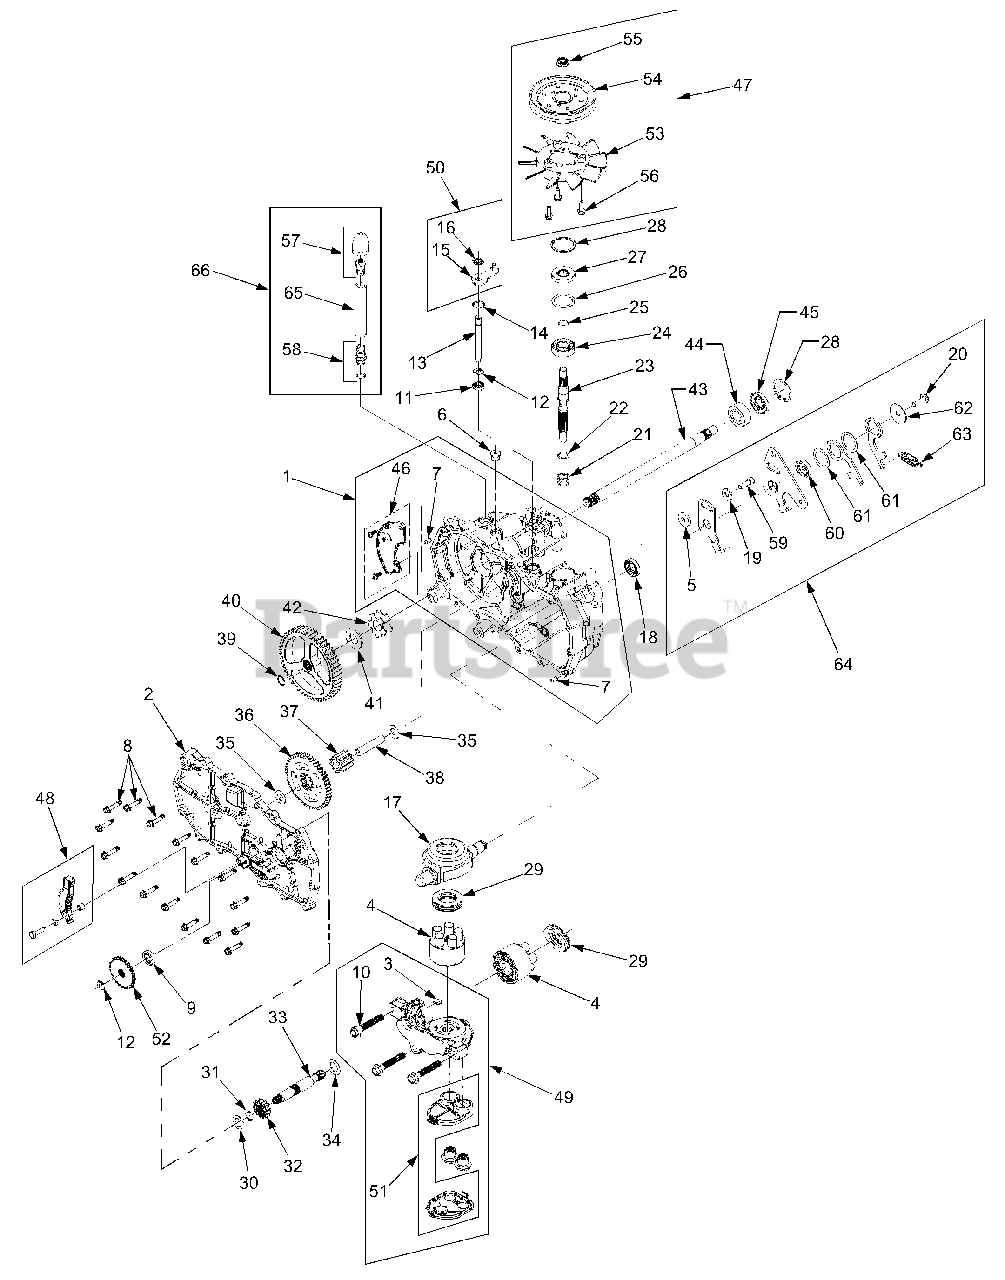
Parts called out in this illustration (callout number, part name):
1	Housing Assembly, Main
2	Side Assembly,
3	Plate, Bypass
4	Block Assembly
5	Spacer, .32 x 1.005
8	Screw, Hex Self Tapping, 1/4-20 x 1.25
9	Seal, Lip, .625 x 1.0 x .25
10	Bolt, Hex Flange, 3/8-24 x 2.5
11	Seal, Lip, .375 x .75 x .25
12	Ring, Retaining, .375 Ext.
14	Ring, Retaining, .75 Int.
16	Ring, Retaining, .375 Push
17	Swashplate, Trunnion
18	Seal, Lip, 18 x 32 x 7
19	Washer, Flat, 11/32 x 7/8 x 1/16
20	Screw, 5/16-24 x 1.0
21	Spring, Compression
22	Washer, .591 x .787 x .04
23	Shaft, Input
24	Bearing, Ball, 17mm x 40 x 12
25	Ring, Wire Retaining, .561
27	Seal, Lip, 17 x 40 x 7
28	Ring, Retaining
29	Bearing, Thrust, 30 x 52 x 13
30	Washer, Flat, 5/8 x 1.0 x .05
31	Ring, Retaining
32	Gear, Pinion, 13T
33	Shaft, Motor
34	Washer, .71 x 1.16 x .04
35	Washer, HT, .5 x 1.0 x .032
36	Gear, 10T/48T
37	Gear, Jackshaft, 10T
38	Pin, Jackshaft
39	Ring, Spiral Retaining
40	Gear, Bull, 52T
41	Washer, 3/4 x 1.5 x .13
42	Bearing, Sleeve
43	Axle
44	Bushing, .752 x 1.571 x .625
45	Seal, Lip, .75 x 1.577 x .25
46	Kit, Expansion Plate
47	Kit, Fan-Pulley
48	Kit, Brake Arm
49	Kit, Center Section-Filter
50	Kit, Bypass Arm
51	Kit, Filter
52	Disc, Brake Cog
53	Fan, 6" 10 Blade
54	Pulley Kit, 4.5
55	Nut, Hex Insert Lock, 1/2-20
56	Screw, Hex Wash. Hd. Tapp 1/4-20
57	Cap Assembly, Vent
58	Fitting/O-ring Assembly
59	Screw, Patch, 5/16-24 x 1.0
60	Bushing, Pilot, 1.125
61	Washer, Plastic
62	Washer, 1.5 x .34 x .062
63	Spring, Extension
64	Kit, Return Assembly
65	Hose, .5 x 4.0
66	Kit, Breather Assembly
